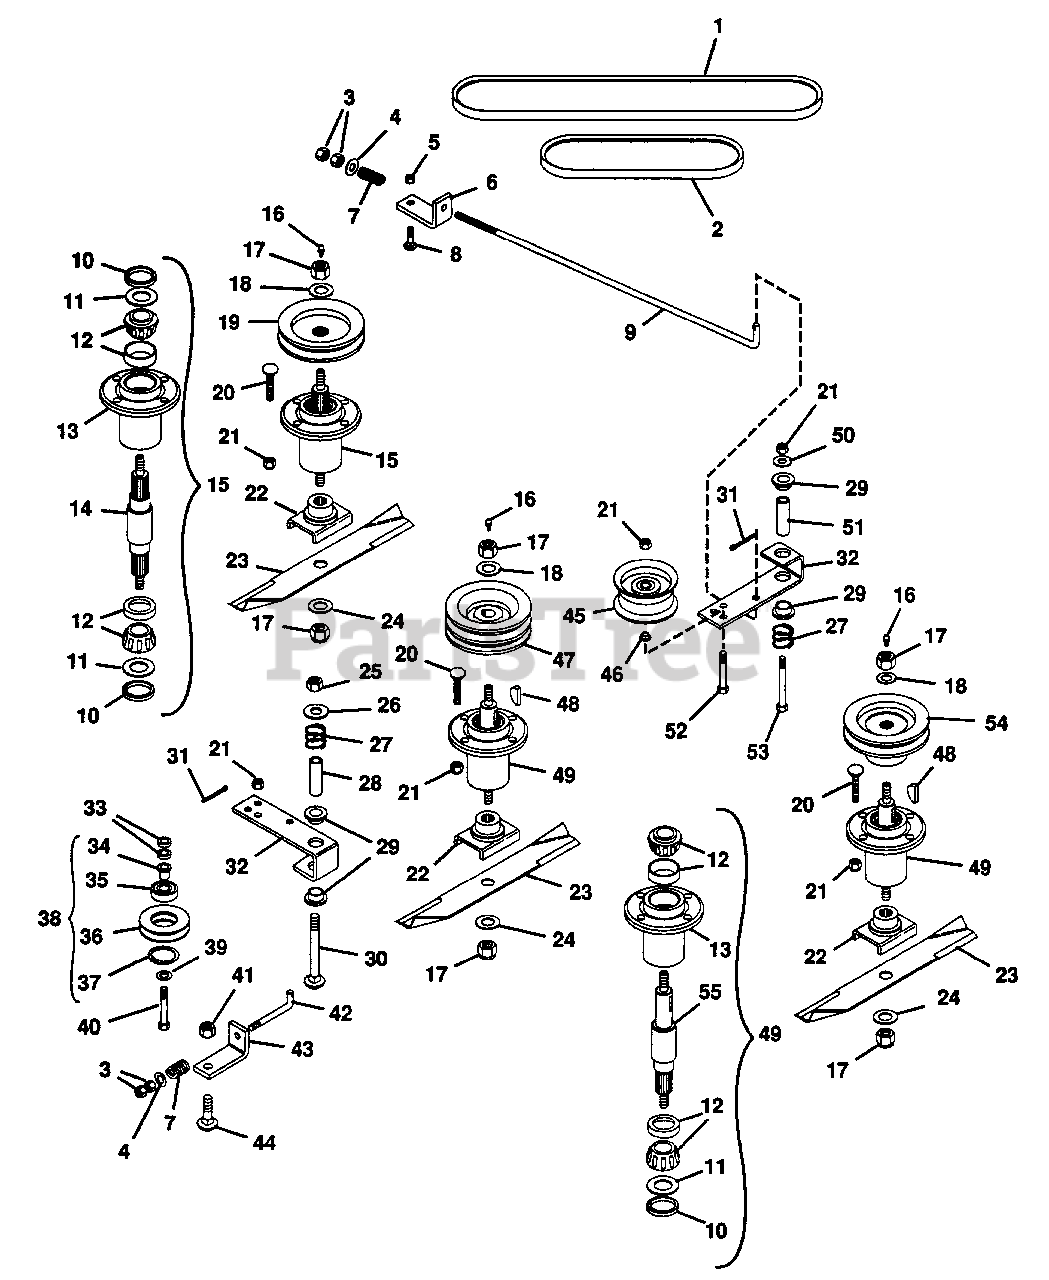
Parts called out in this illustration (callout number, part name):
1	Belt, Pro Mower
2	Belt, Mower A44
3	Nut, Hex 3/8-16
4	Washer, Flat .406x.812x.065
5	Nut, Lock 5/16-18
6	Bracket, Belt Tensioner
7	Spring, Comp. 1x.78x338 Lb/N
8	Bolt, Carriage 5/16-18x1.00
9	Rod, Idler
10	Seal, Steel(Left & Center Spindles)
10	Seal, Steel(Right Spindle)
11	Washer, Flat .975x1.970x.030(Left & Center Spindles)
11	Washer, Flat .975x1.970x.030(Right Spindle)
12	Assembly, Bearing
13	Housing, Bearing
14	Shaft, Spindle
15	Assembly, Spindle
16	Fitting, Lube 1/8
17	Nut, Lock 5/8-11
18	Washer, Flat .687x1.312x.122
19	Sheave, Spindle
20	Bolt 3/8-16x1.37 Rd Hd Sq Nk
21	Nut, Lock 3/8-16
22	Weldment, Blade Cradle
23	Blade
24	Washer, Flat .656x1.312x.095
25	Nut, Lock 1/2-13
26	Washer, Flat .531x1.250x.100
27	Spring, Comp. 1x.80x36 Lb/N
28	Bush., St. .560x.750x2.44 Stl.
29	Bush., Flg. .764x1.47x.560 Ny.
30	Bolt, 1/2-13x3.50 Rd Hd Sq Nk
31	Pin, Cotter .09x.75
32	Arm, Idler Pivot
33	Bush., St. .406x.750x.188 Stl.
34	Bush., Flg. .391x1.00x.760 Stl.
35	Bearing, Ball
36	Sheave, Idler
37	Ring, Retaining
38	Assembly, Idler Sheave
39	Washer, Flat .375x1.125x.065
40	Bolt, Hex 3/8-16x2.00
41	Nut, Lock 1/2-13
42	Rod, Idler
43	Bracket, Belt Tensioner
44	Bolt, 1/2-13x1.50 Rd Hd Sq Nk
45	Pulley, Idler
46	Bush., Flg. .406x.880x.270 Br.
47	Sheave, Spindle
48	Key, Woodruff .250x1 Hard #15
49	Assembly, Spindle
50	Washer, Flat .438x1.000x.083
51	Bush., St. .437x.750x2.44 Stl.
52	Bolt, Hex 3/8-16x2.25
53	Bolt, Hex 3/8-16x3.25
54	Sheave, Spindle
55	Shaft, Spindle
